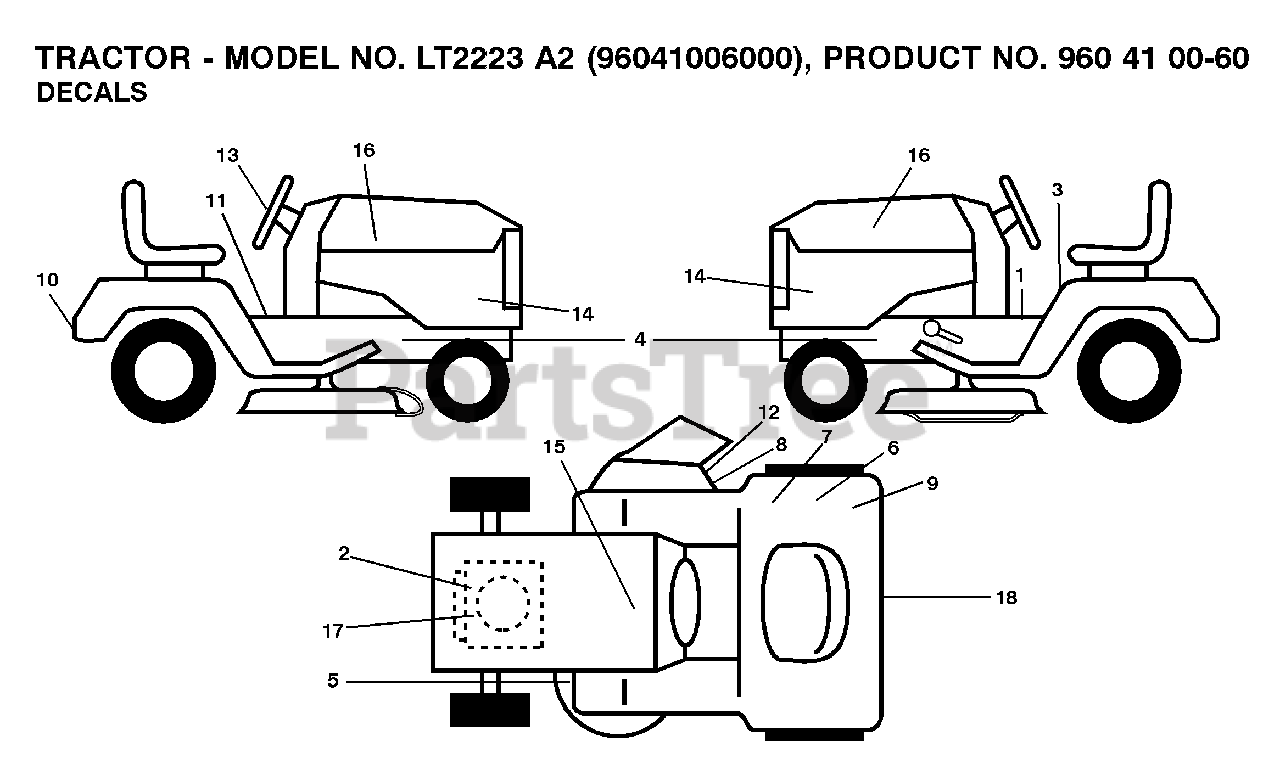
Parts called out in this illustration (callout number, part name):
1	DECAL PARK BRAKE
5	DECAL V BELT SCHEMATIC
7	DECAL.80 DBA.AUSTRALIA
8	DECAL, DEFLECT WARNING
12	DECAL.INTERNATIONL.CUTFINGER
15	DECAL BTRY SYMBOLS
